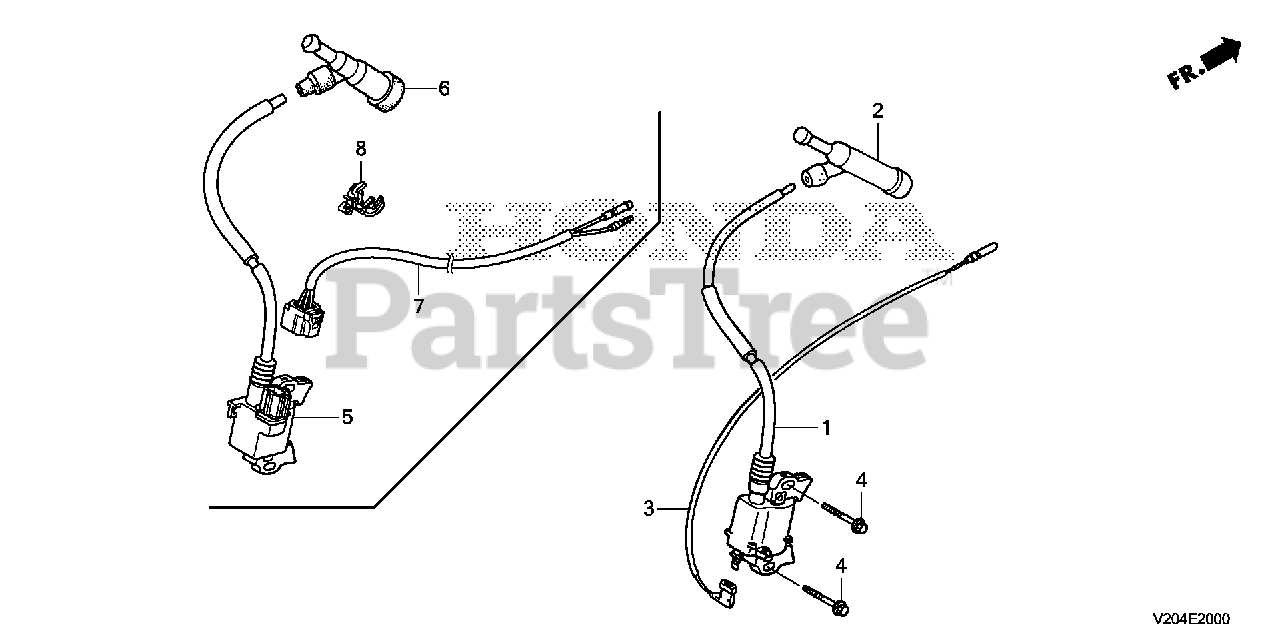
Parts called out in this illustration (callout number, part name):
4	BOLT, FLANGE (6X28) (CT200) Use up to Engine SN 1530314.
5	COIL ASSY., IGNITION
6	CAP ASSY., NOISE SUPPRESSOR (NGK Y-EZD)
7	WIRE HARNESS ASSY., ENGINE
8	CLIP, WIRE HARNESS
